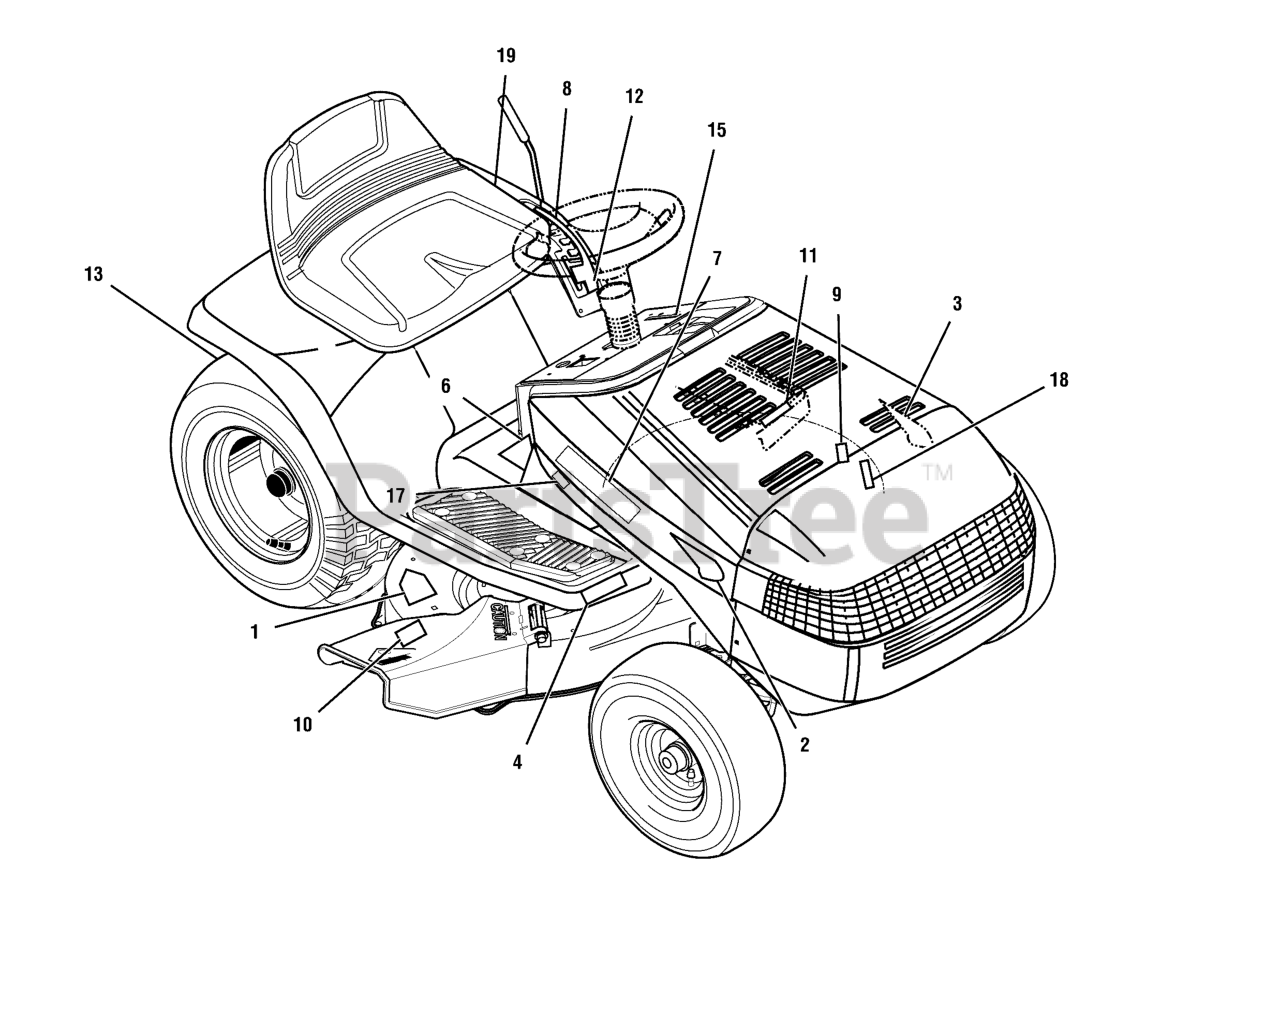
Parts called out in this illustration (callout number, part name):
1	DECAL, CUT FINGER ENGLISH
2	DECAL, MASPORT 12.5/38 RH
3	DECAL, MASPORT 12.5/38 LH
4	DECAL, 5 SPEED
6	DECAL, WARNING
7	DECAL, MASPORT LOGO
8	DECAL, 1/6 HGT ADJ-LIFT
9	DECAL, NO STEP-LH HSNG
10	DECAL, NO STEP-CHUTE
11	DECAL, CLUTCH/BRAKE SILVER
12	DECAL, DECK LEVEL POS/ONLY
13	DECAL, WARNING LOAD LMT
15	DECAL, DASH SYMBOLS 3510
17	DECAL, V2-SS-1X3 CUTTING HEIGHT
18	DECAL, 3 WAY
19	DECAL, ENGAGE PTO
